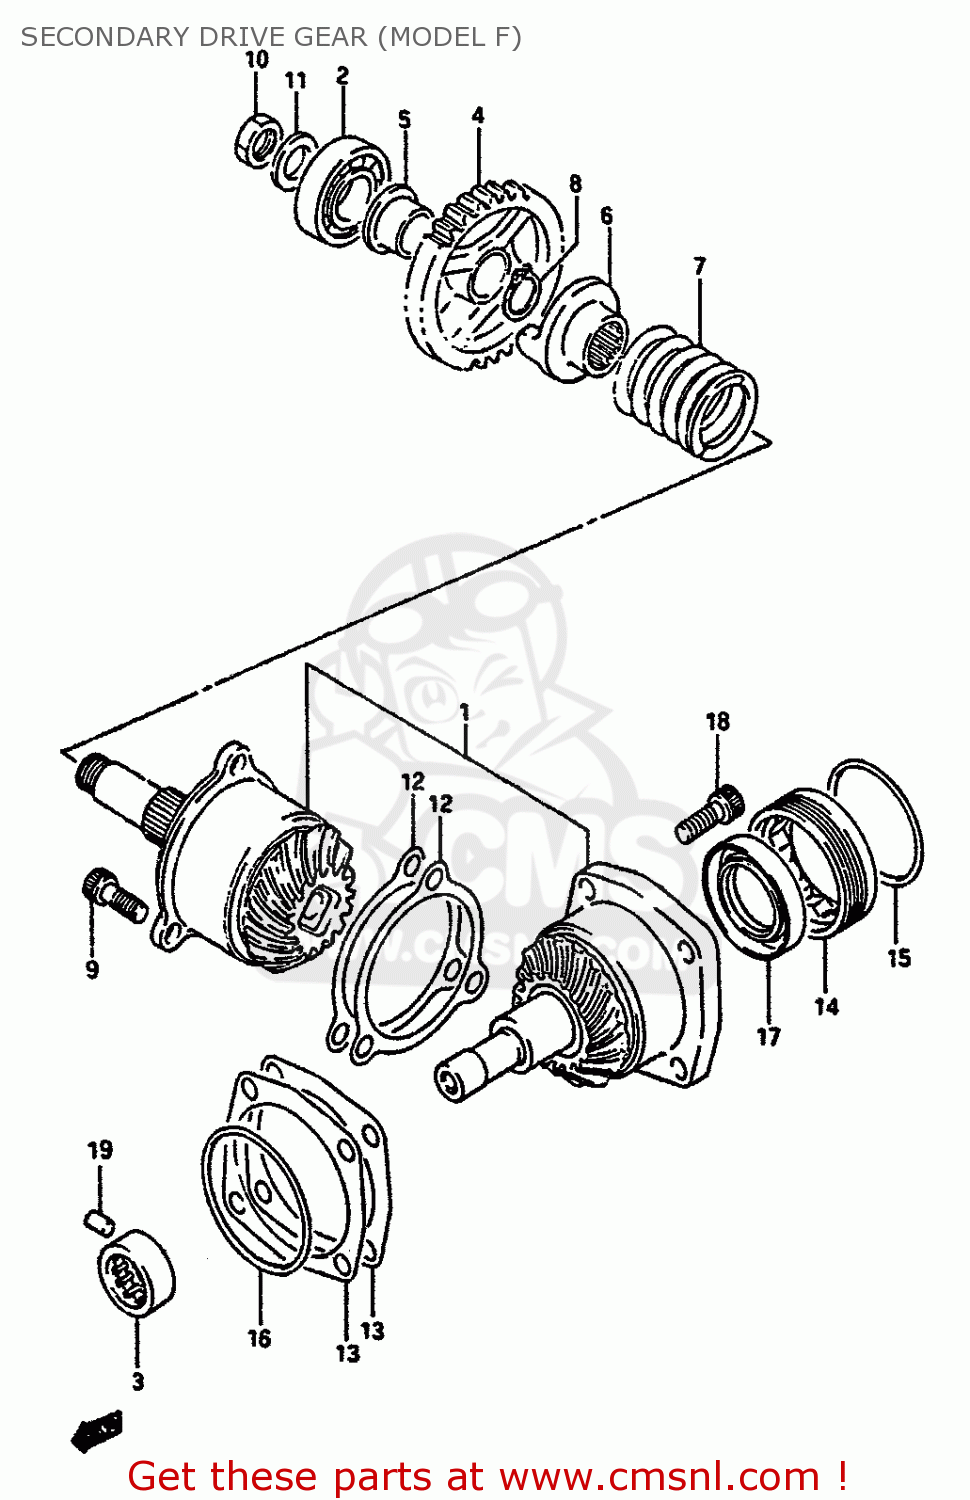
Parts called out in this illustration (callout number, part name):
1	GEAR,SECONDARY & HOUSING
2	BEARING(20X52X15)
3	BEARING(20X34X16)
4	GEAR,REDUCTION DRIVEN(NT:30)
5	BUSH,REDUCTION DRIVEN GEAR
6	DOG,OUTPUT CAM
7	SPRING
8	CIRCLIP,21MM
9	BOLT
10	NUT
11	WASHER(16X29X4)
12	SHIM,SECONDARY DRIVE
13	SHIM,SECONDARY DRIVEN HOUSING
14	STOPPER,SECONDARY DRIVEN BEARING
15	O RING(D:1.9,ID:61.6)
16	O RING(D:2.1,ID:66.2)
17	SEAL,OIL(38X54X6)
18	BOLT
19	PIN
